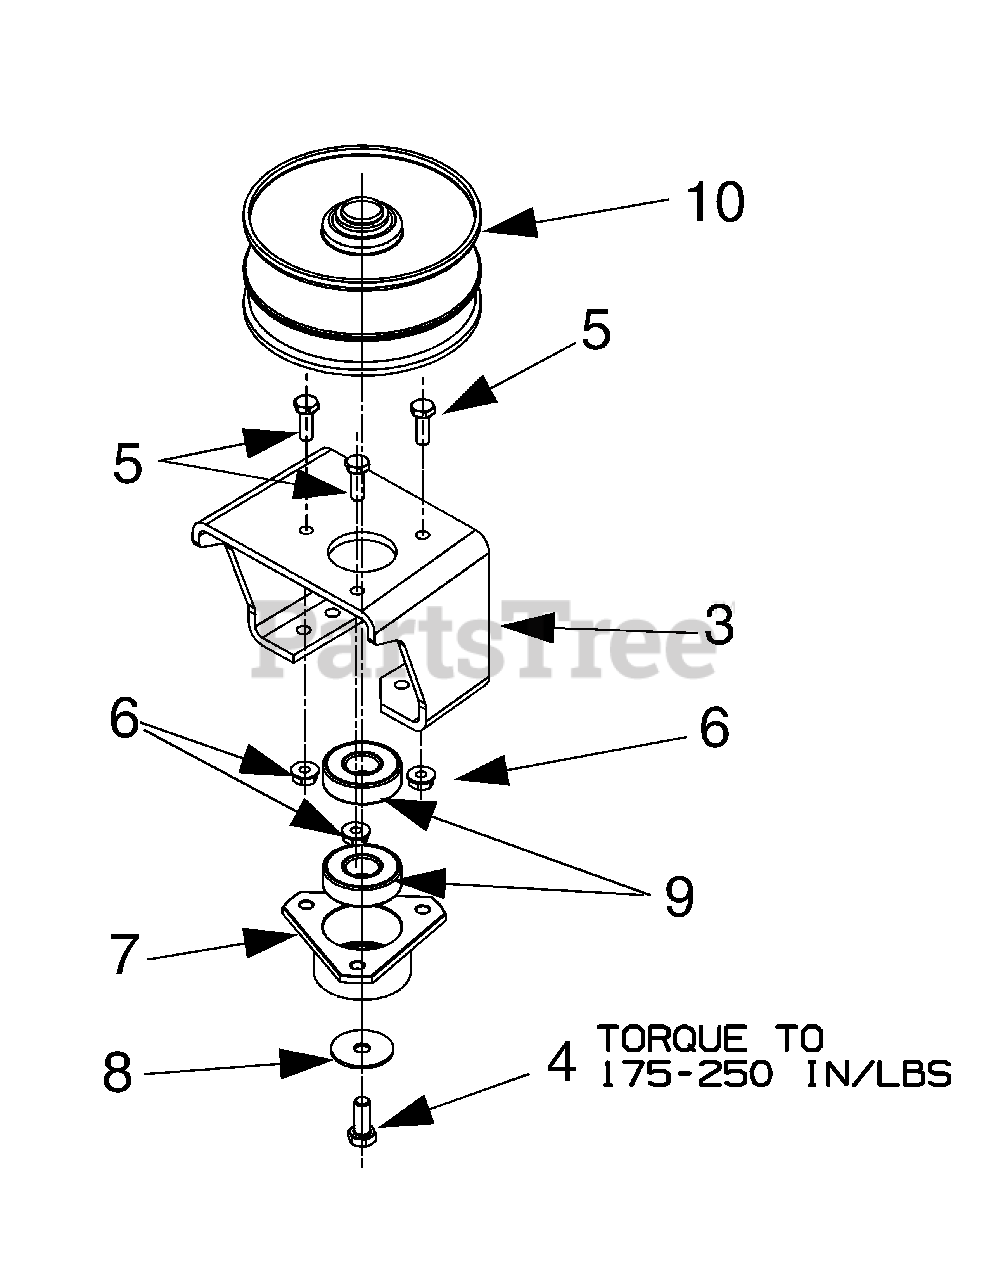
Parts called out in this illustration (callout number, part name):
2	AB SCREW: 5/16-12 x 0.75 (Self-Tap)
3	VARIABLE SPEED BRACKET
4	LOCK BOLT, 5/16"-24 x 0.75"
5	HEX BOLT, 1/4"-20 x 0.75"
6	FLANGED LOCK NUT
7	BEARING CUP
8	FLAT WASHER
9	BALL BEARING
10	VARIABLE SPEED PULLEY
